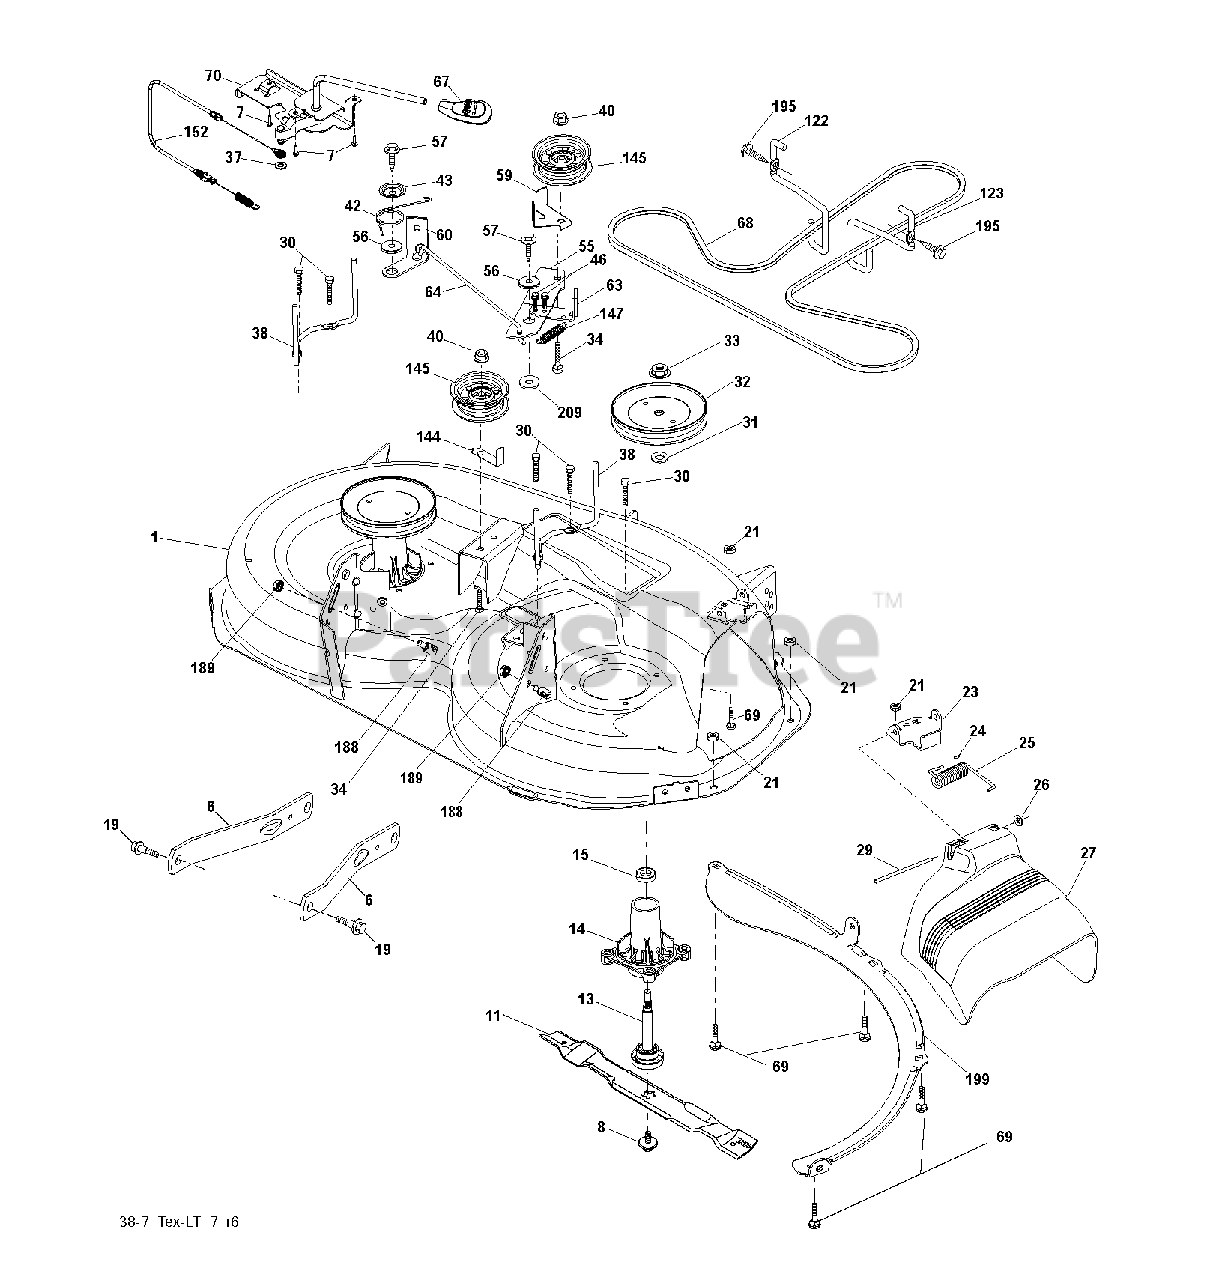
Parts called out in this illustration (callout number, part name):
6	ARM.SUSPENSION.MOWER.R
7	SCREW.#10 X 0.750.BOS THREAD
8	BOLT.WASHER.ASM.7/16-2
11	BLADE 38" PREMIUM
13	SHAFT.ASM.MDRL.N/GREASE.38
14	HOUSING MANDREL
19	BOLT.SHOULDER
21	LOCKNUT
23	BRKT.DEFLECTOR.38"2005+
24	CAP-SLEEVE LT
25	SPRING.TORSION.DEFLECT
26	NUT PUSH M
29	ROD.HINGE
30	SCREW, WASHER HEAD
31	WASHER.SPACER.MANDREL
32	PULLEY.MANDREL.5.0.PD.38"
33	NUT.FLANGE.LOCK.TOP
34	BOLT.3/8-16X1.50
38	KEEPER BELT LH MANDREL
40	NUT LOCK FLG 3/8-16 UNC
42	SPRING.TORSION.BRAKE
43	SRPING.TORSION.RETAINE
46	SCREW.1/4-20X5/8
55	IDLER.ARM
56	SPACER.RETAINER
57	SCREW 3/8-16X1
59	GUARD, BELT
60	ARM BRAKE MOWER RH 38"
63	ARM BRAKE MOWER RH
64	LINK BRAKE
67	HANDLE.CLUTCH.CABLE.LT
69	BOLT
70	CLUTCH.ASM.MANUAL.LT.PRED
122	KEEPER BELT ENGINE LH
123	KEEPER BELT RH
144	KEEPER BELT
145	PULLEY.IDLER.48"PRIMARY
147	SPRING RETURN
152	CLUTCH CABLE
188	STUD.FASTNER.W/ANTI-ROTATE
189	NUT LOCK HEX FLANGE 5/16-18
195	SCREW, 3/8-16X3/4
199	BAFFLE VORTEX
209	WASHER 12/32X2X10GA
